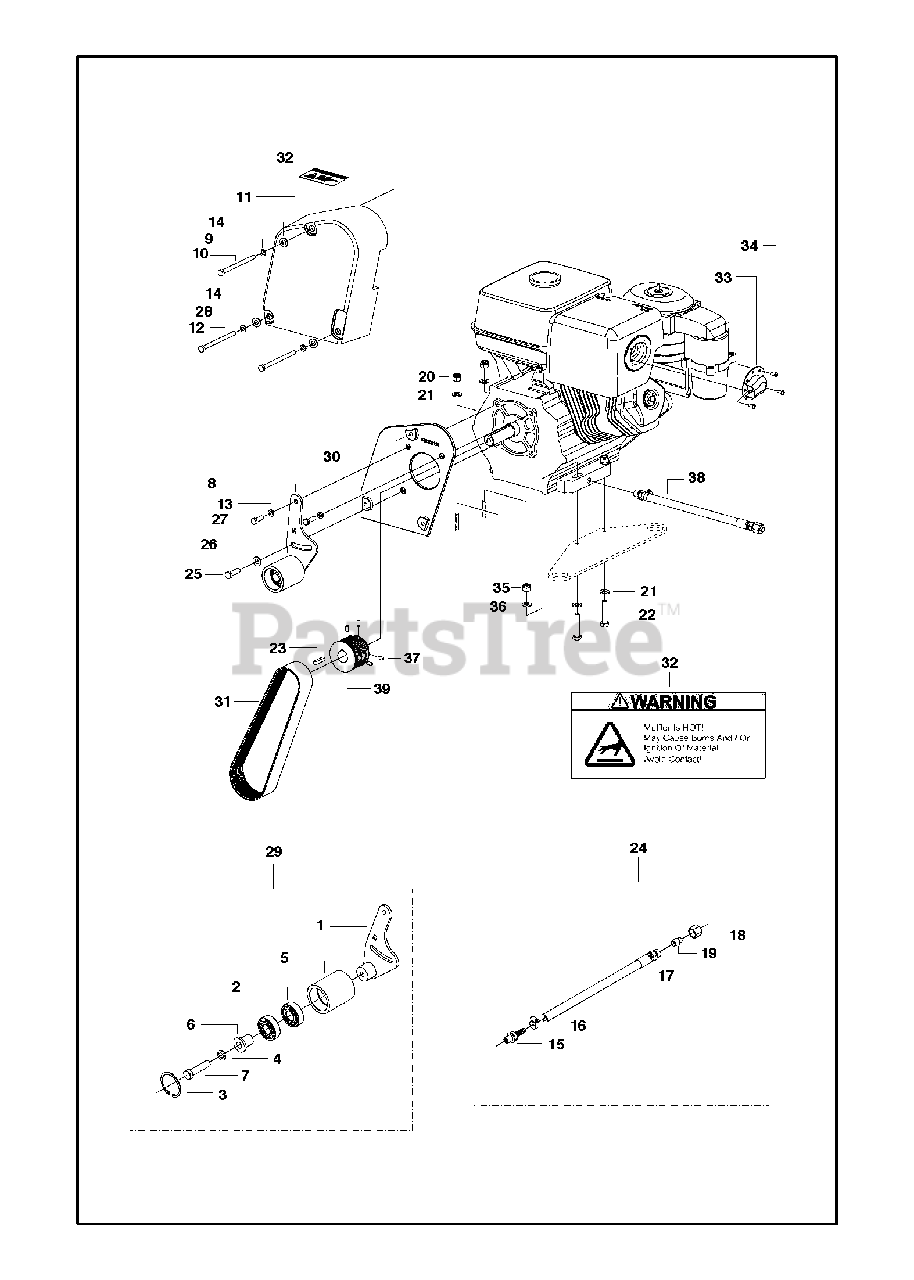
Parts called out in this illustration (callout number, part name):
8	IDLER SHEAVE ASSEMBLY
9	SPRING WASHER
13	SPRING WASHER
14	WASHER
16	CLAMP, HOSE, MAH-4 FUEL LINE
20	HEXAGON LOCKING NUT
21	WASHER
28	SPRING WASHER
29	IDLER SHEAVE ASSEMBLY
34	SCREW CCRPANT
35	HEXAGON LOCKING NUT
36	WASHER
